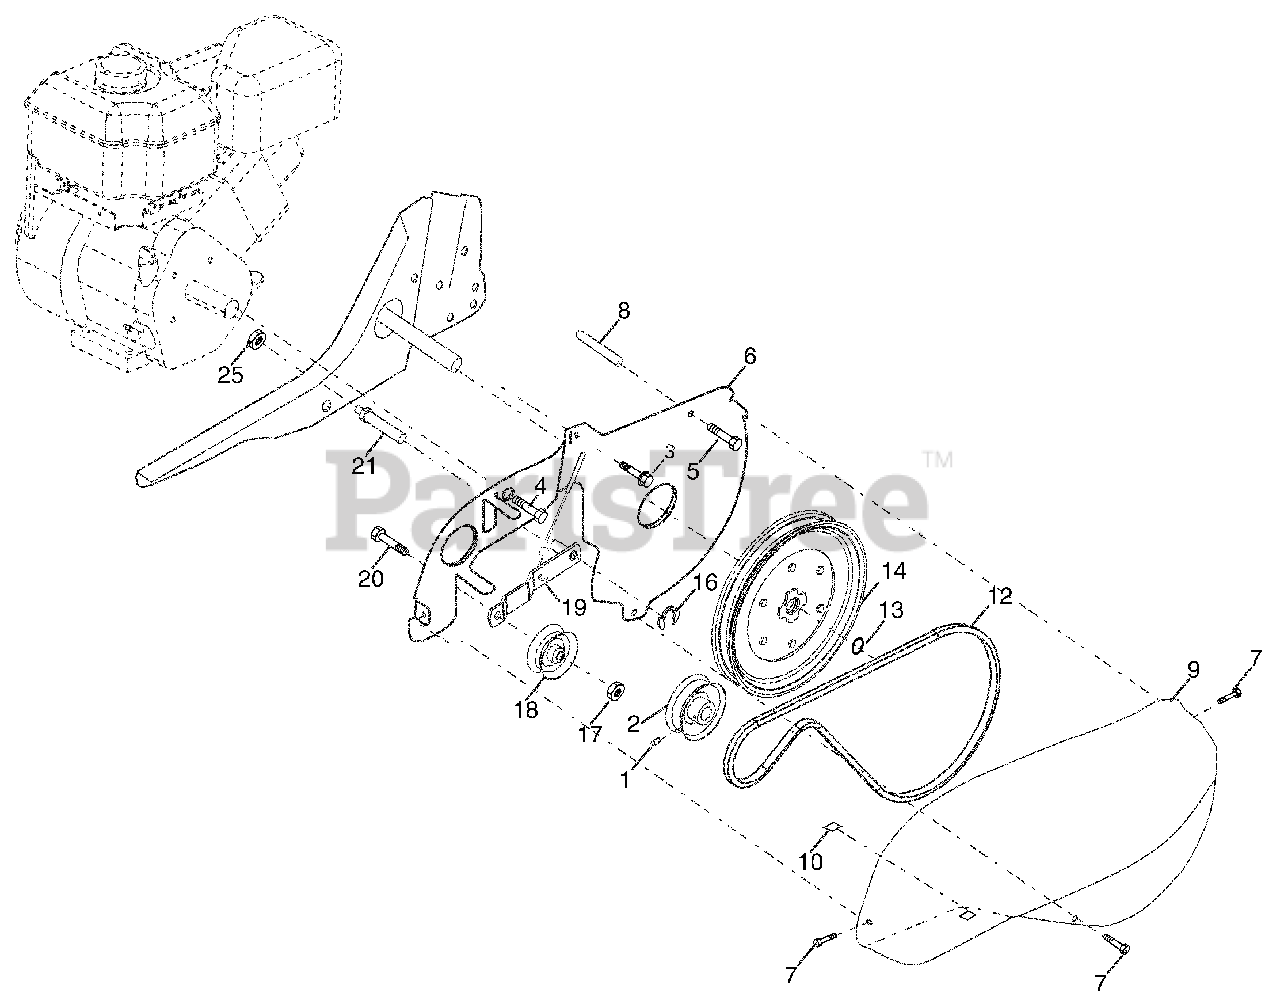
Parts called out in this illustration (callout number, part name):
1	Screw, Set 5/16-18 x 3/8
2	Sheave, Engine
4	Bolt, Hex 1/2-20 x 3/4
5	Bolt Thd Roller 1/4-20 X 2-1/2
6	Shield Inner Guard Belt
7	Screw Hex Wsh Slt #10-24 x .50
8	Spacer Split .523 x .718 x 2
9	Guard, Belt
10	Pad, Idler
12	V-Belt Drive
13	Ring, Retainer
14	Sheave, Transmission
16	Ring, Klip
17	Nut, Hex, Jam 3/8-16
18	Pulley, Idler
20	Bolt, Hex 3/8-16 x 1-1/4
21	Shaft, Idler Arm
25	Nut, Hex, Jam 5/16-18
